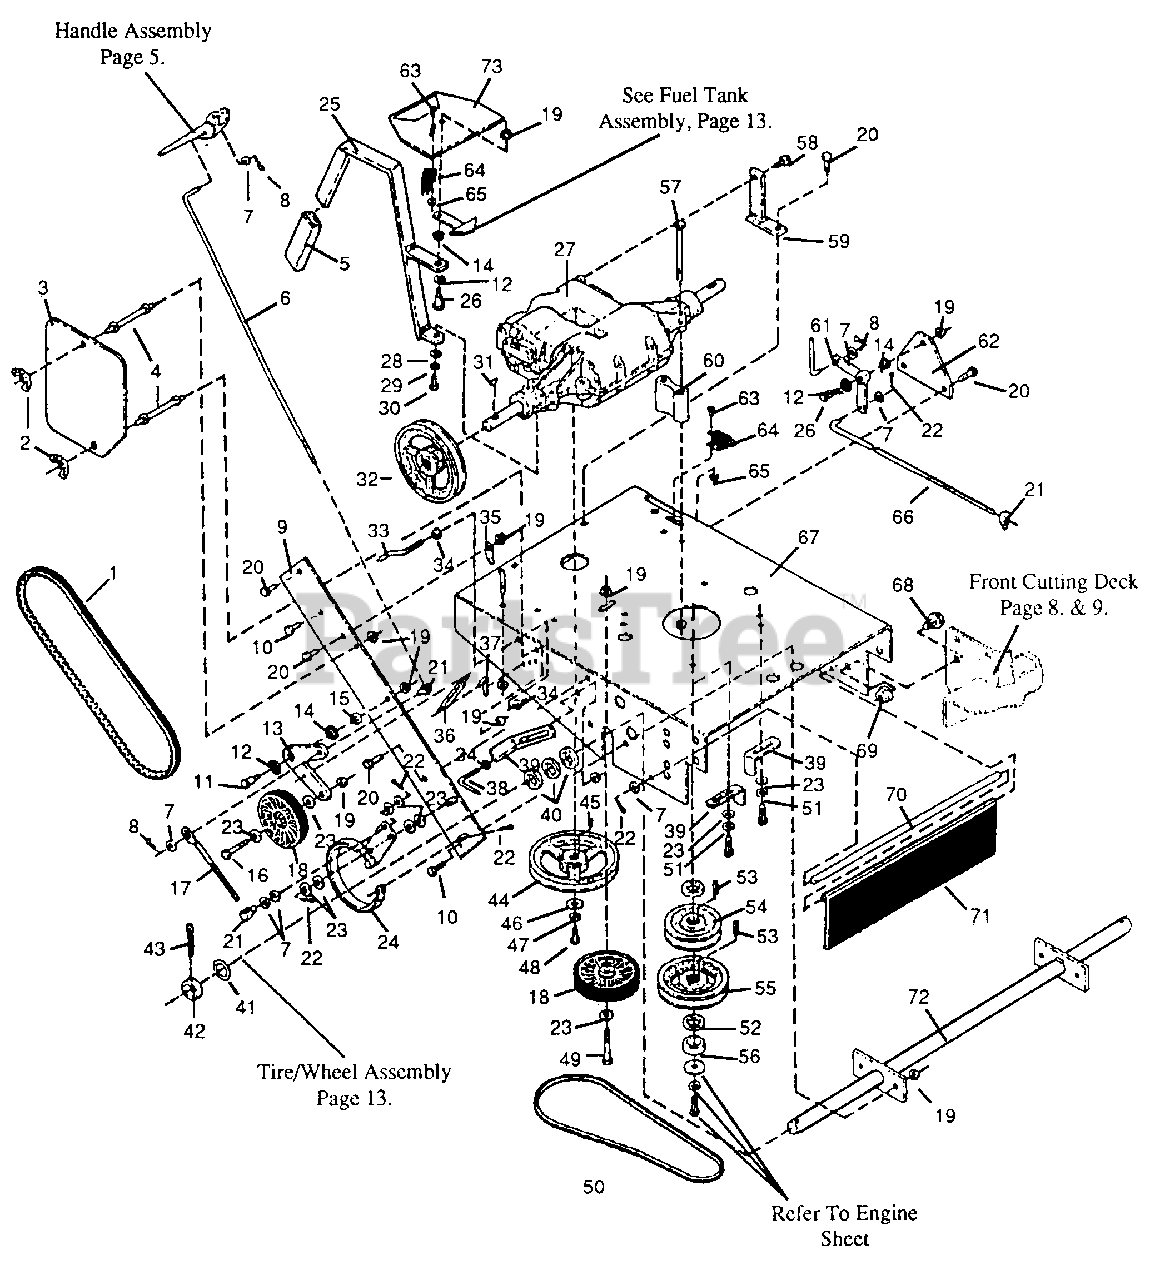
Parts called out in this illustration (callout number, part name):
1	Belt, Traction
2	Wing Nut
3	Tracbon Guard
4	Stud, Traction Guard
5	Gnp, Flat Handle
6	Traction Control Rod
7	5/16- Flat Washer
8	Hair Pin Clip
9	Lower Handle, Left
10	3/8"-16 x 1 Hex Hd Cap Screw
11	Shoulder Bolt
12	Belleville Disc Washer
13	Bellaank - Acute Angle
14	Snap-ln Bushing
15	Spacer - Shoulder
16	3/8 -16 x 2- Hex Hd Cap Screw
17	Rod, Brake
18	Idler Pulley
19	3/8 -16 Flange Nut
20	3/8"- 16 x 3v4 Hex Hd Cap Screw
21	Swivel
22	3/32 x 1/2- Cotter Pin
23	3/8 Flat Washer
24	Brahe, Traction Wheel, Left
25	Gear Shift Lever
26	Shoulder Bolt
27	Transmission
28	1/4- Flat Washer
29	1/4 Spring Lock Washer
30	1/4 - 28 x 1/2' Hex Hd Cap Screw
31	Woodruff Key
32	Sheave, Transmission Output
33	Belt guide
34	5/16 -18 Flange Nut
35	Support Rod
38	Scrapper
39	Beltguide
40	7/8 Flat Washer
41	7/8' Machinery Bushing
42	Collar, Axle
43	3/16' x 2' Cotter Pin
44	Sheave, Transmission Input
45	#9 Woodnuff Key
46	Washer, Special
47	1/4' Spring Lock Washer
48	1/4' - 20 x 5/8' Hex. Hd. Cap Screw
49	3/8' -16 x 1-3/4' Hex. Hd. Cap Screw
50	Belt. Transmission Input
51	3/8' Spring Lock Washer
52	1/4' Engine Sheave Spacer
53	1/4' x 1/4' x 1' Square Key
54	Pulley, Engine To Transmission
55	Pulley, Engine To Blade
56	7/16' Engine Sheave Spacer
57	5/16' -18 x 4-3/4' Hex. Hd. Cap Screw
58	5/16' -18 x 3/4' Self-Tapping Screw
59	Transmission Support
60	Spacer, Transmission Mount
61	Bellaank- 90 Degree Legs
62	Brkt., Blade Engagement Bellcrank
63	10 - 24 x 1/2' Pan Hd. Mach. Screw
64	Interlock Switch
65	10 - 24 Keps Nut
66	Rod, Blade Engagement
67	Frame, Power Deck Unit
68	1/2' -13 x 1' Hex. Hd. Cap Screw
69	1/2' -13 Flange Nut
70	Rod, Safety Flap
71	Safety Flap
73	Gear Selector Plate W/Decal
